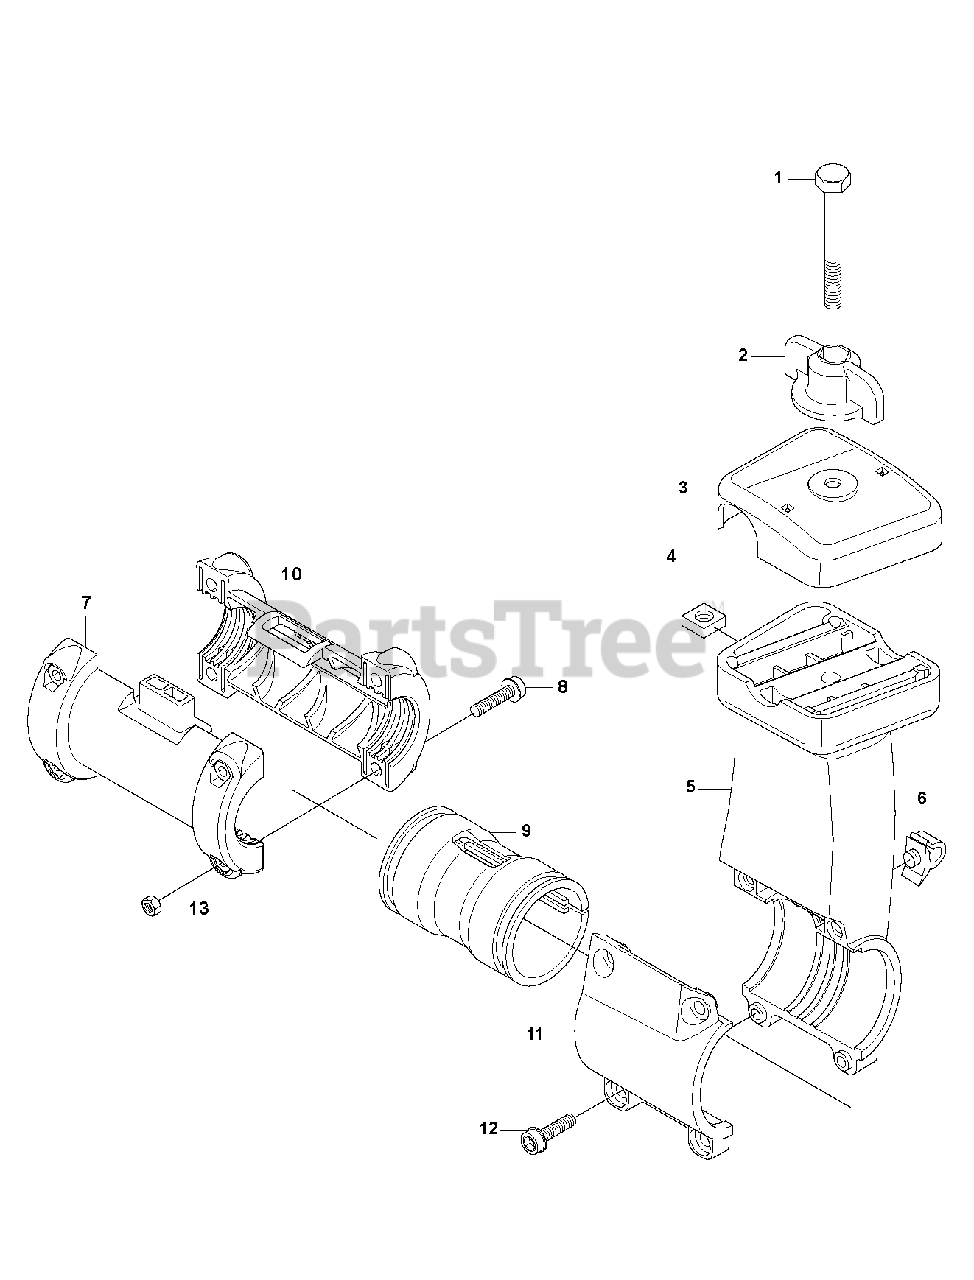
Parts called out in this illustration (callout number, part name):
5	BRACKET ASSY
7	CLAMPING SLEEVE
9	VIBRATIONS ABSORBER
10	CLAMPING SLEEVE ASSY
12	SCREW
